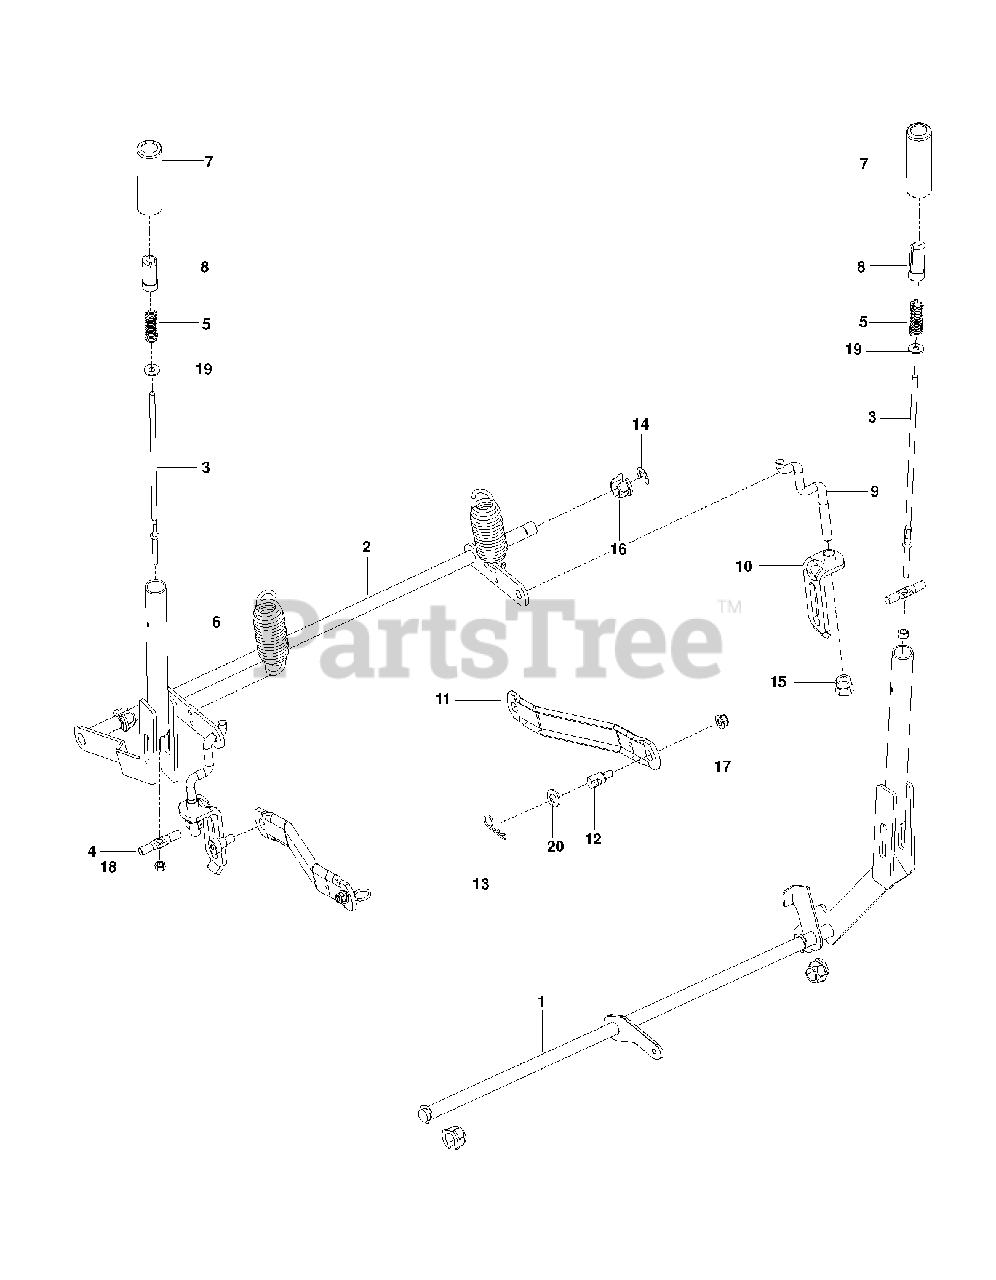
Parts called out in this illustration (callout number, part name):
1	SUB.ASM.SHAFT.BRAKE.WLDMNT.MED
2	SHAFT, LIFT, BLACK
3	ROD, HANDLE RELEASE
4	RB ROD, LATCH RELEASE
5	SPRING, COMPRESSION
7	GRIP, HANDLE, BLACK 4"
8	BUTTON, PUSH, BLACK
9	LINK, REAR SUSPENSION
10	ASSEMBLY, BRKT LINK
11	ARM.SUSPENSION.MOWER
12	STUD.FASTNER.W/ANTI-ROTATE
13	HAIRPIN #4
14	E-RING 5/8
15	NUT, LIFT LINK 7/16-20
16	PLASTIC NUT
17	5/16-18 NYLOC FLANGE NUT
18	LOCKNUT.NYLOC.1/4-20
20	WASHER
